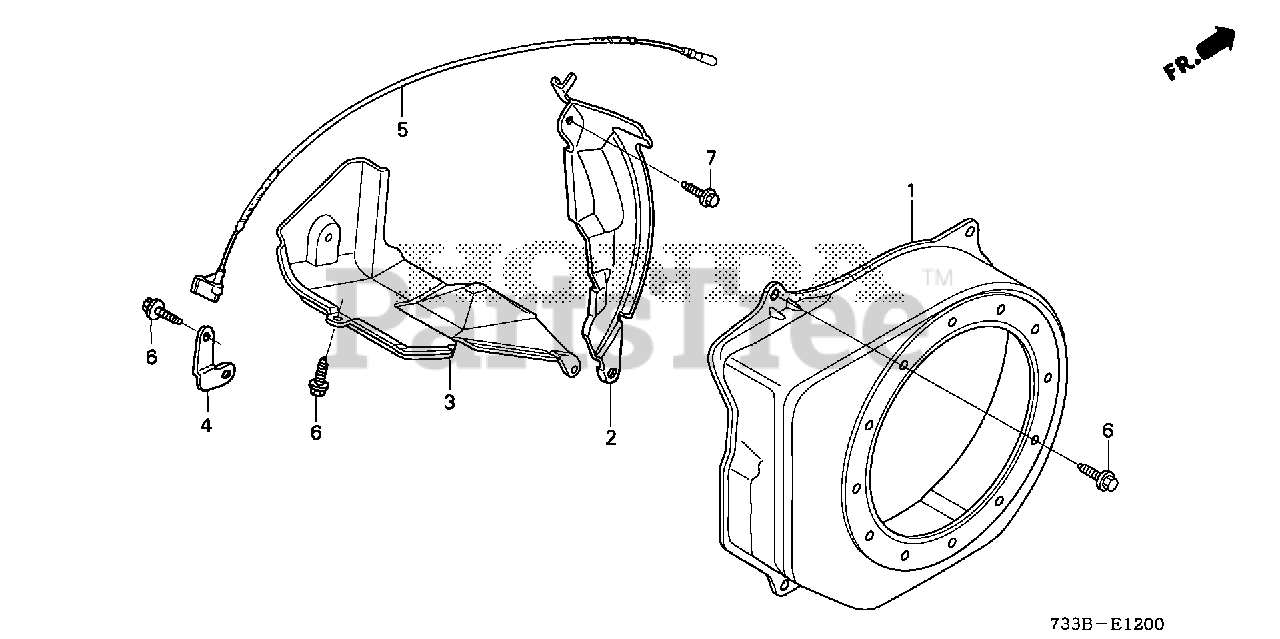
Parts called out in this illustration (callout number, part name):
1	COVER, FAN *R280* (POWER RED)
2	PLATE, SIDE (STD)
3	SHROUD
4	STAY, WIRE CLIP
5	WIRE, STOP SWITCH (370MM)
6	BOLT, FLANGE (6X12) (CT200)
7	BOLT, FLANGE (6X20) (CT200)
